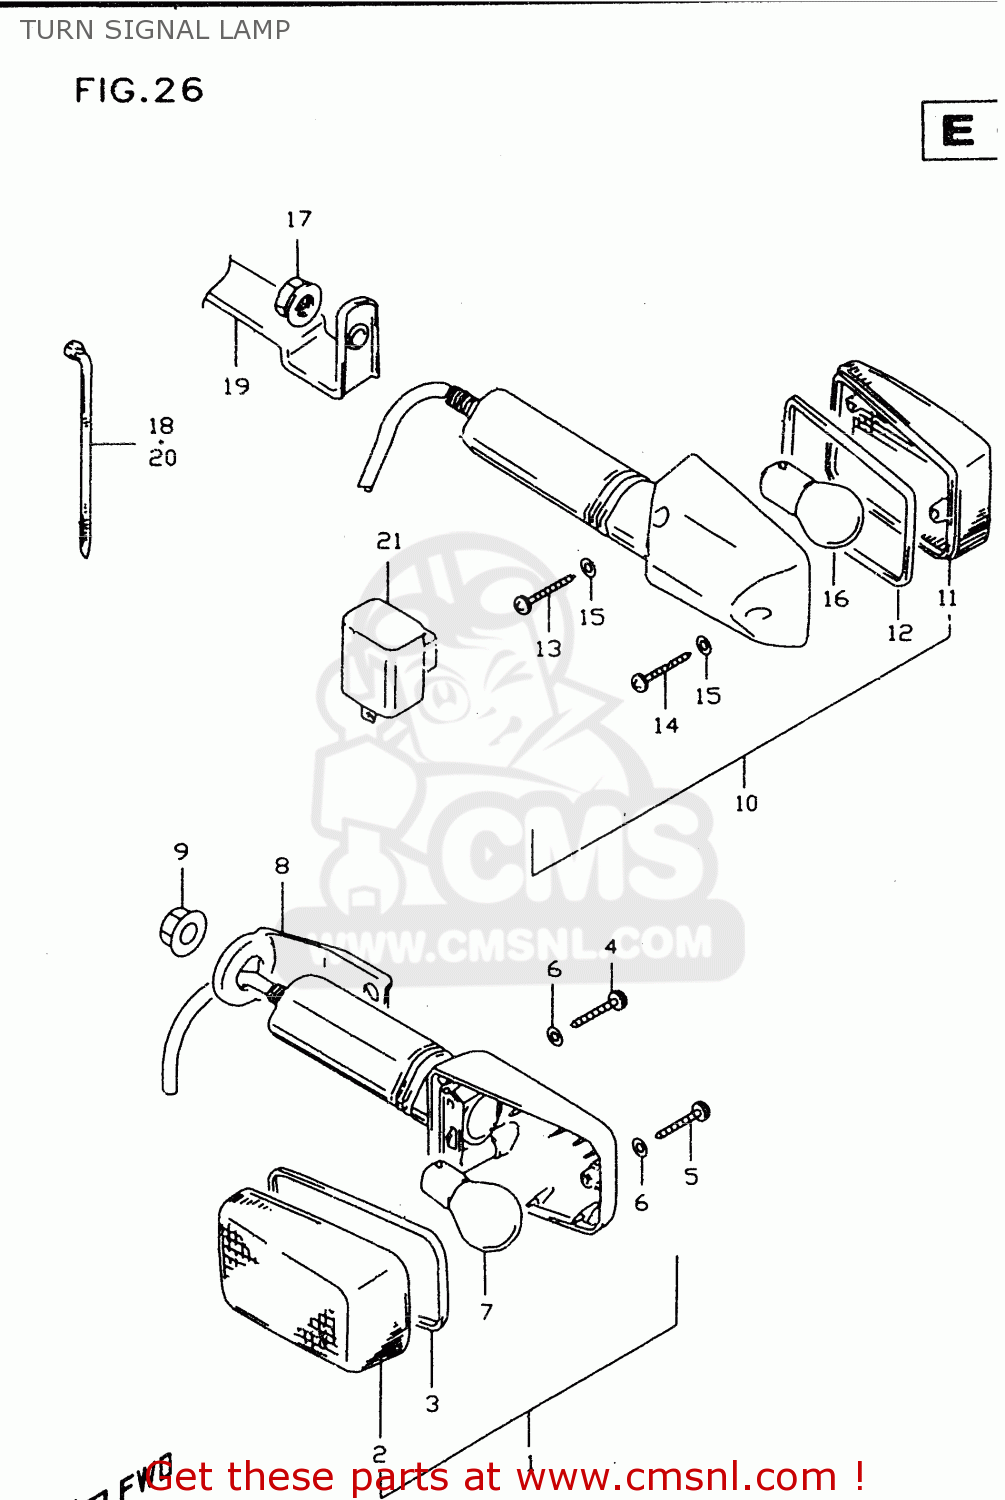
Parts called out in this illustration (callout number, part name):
1	LAMP ASSY,FR TURN SIGNAL
2	LENS
3	GASKET (NAS)
4	SCREW(3X30)
5	SCREW
6	GASKET (NAS)
7	BULB(12V21W)
8	BRACKET,FR TURNSIGNAL,R
9	NUT
10	LAMP ASSY,RR TURNSIGNAL
11	LENS
12	GASKET (NAS)
13	SCREW(3X30)
14	SCREW
15	GASKET (NAS)
16	BULB(12V21W)
17	NUT
18	CLAMP(L:33)
19	BRACKET, RR TURNSIGNAL
20	CLAMP(L:125)
21	RELAY ASSY,TUR
